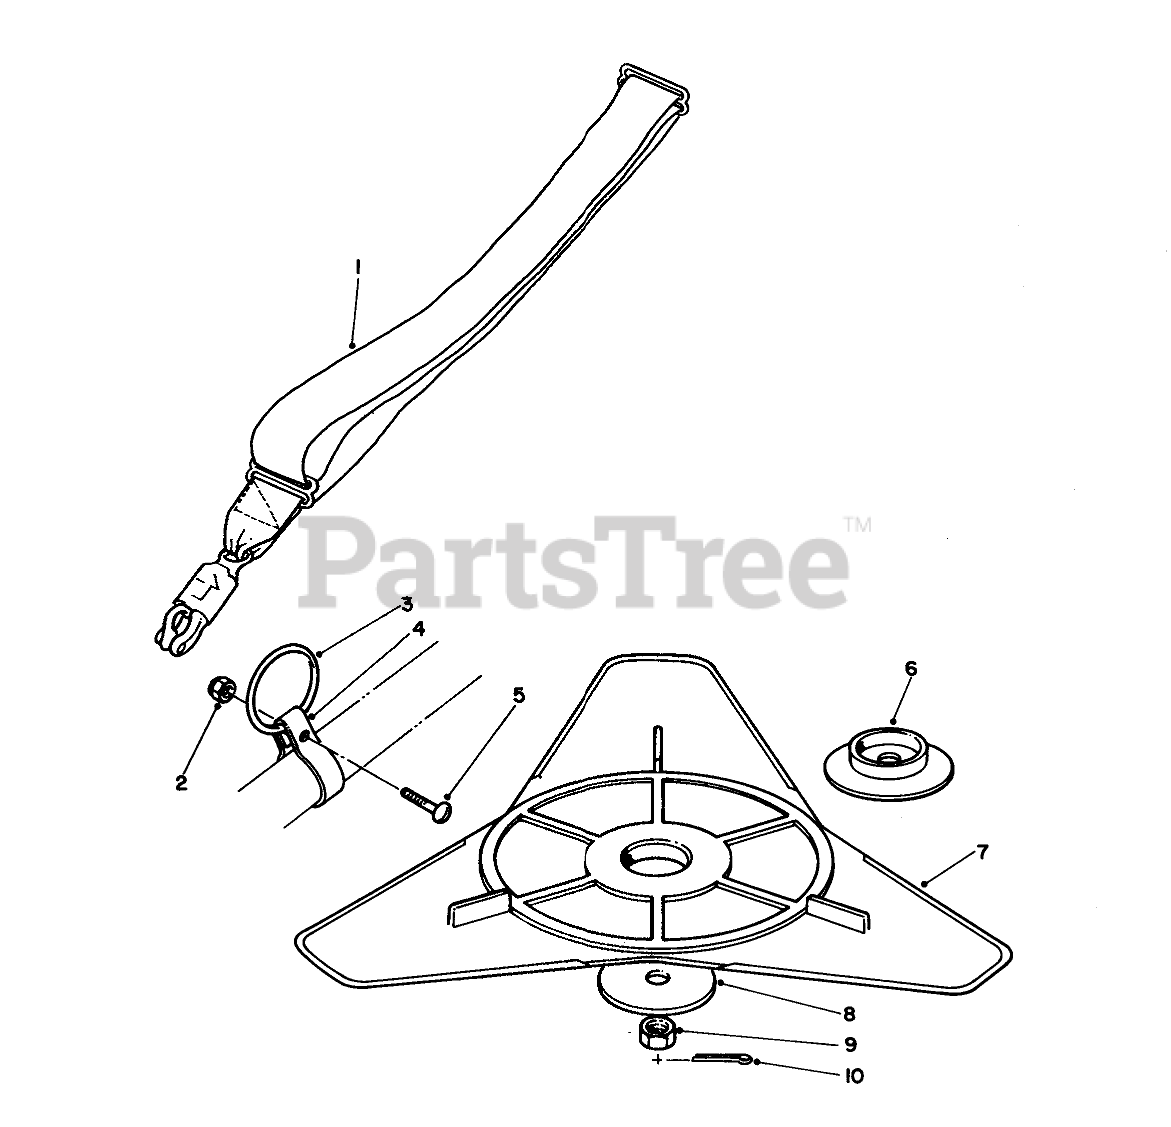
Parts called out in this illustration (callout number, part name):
1	Shoulder Strap
2	NUT-LOCK, NI
3	Ring
4	Clamp
5	10-24 X 5/8 PAN HD MS
6	Adapter-Blade
7	FLEX BLADE PKG
8	WASHER
10	Split Pin
